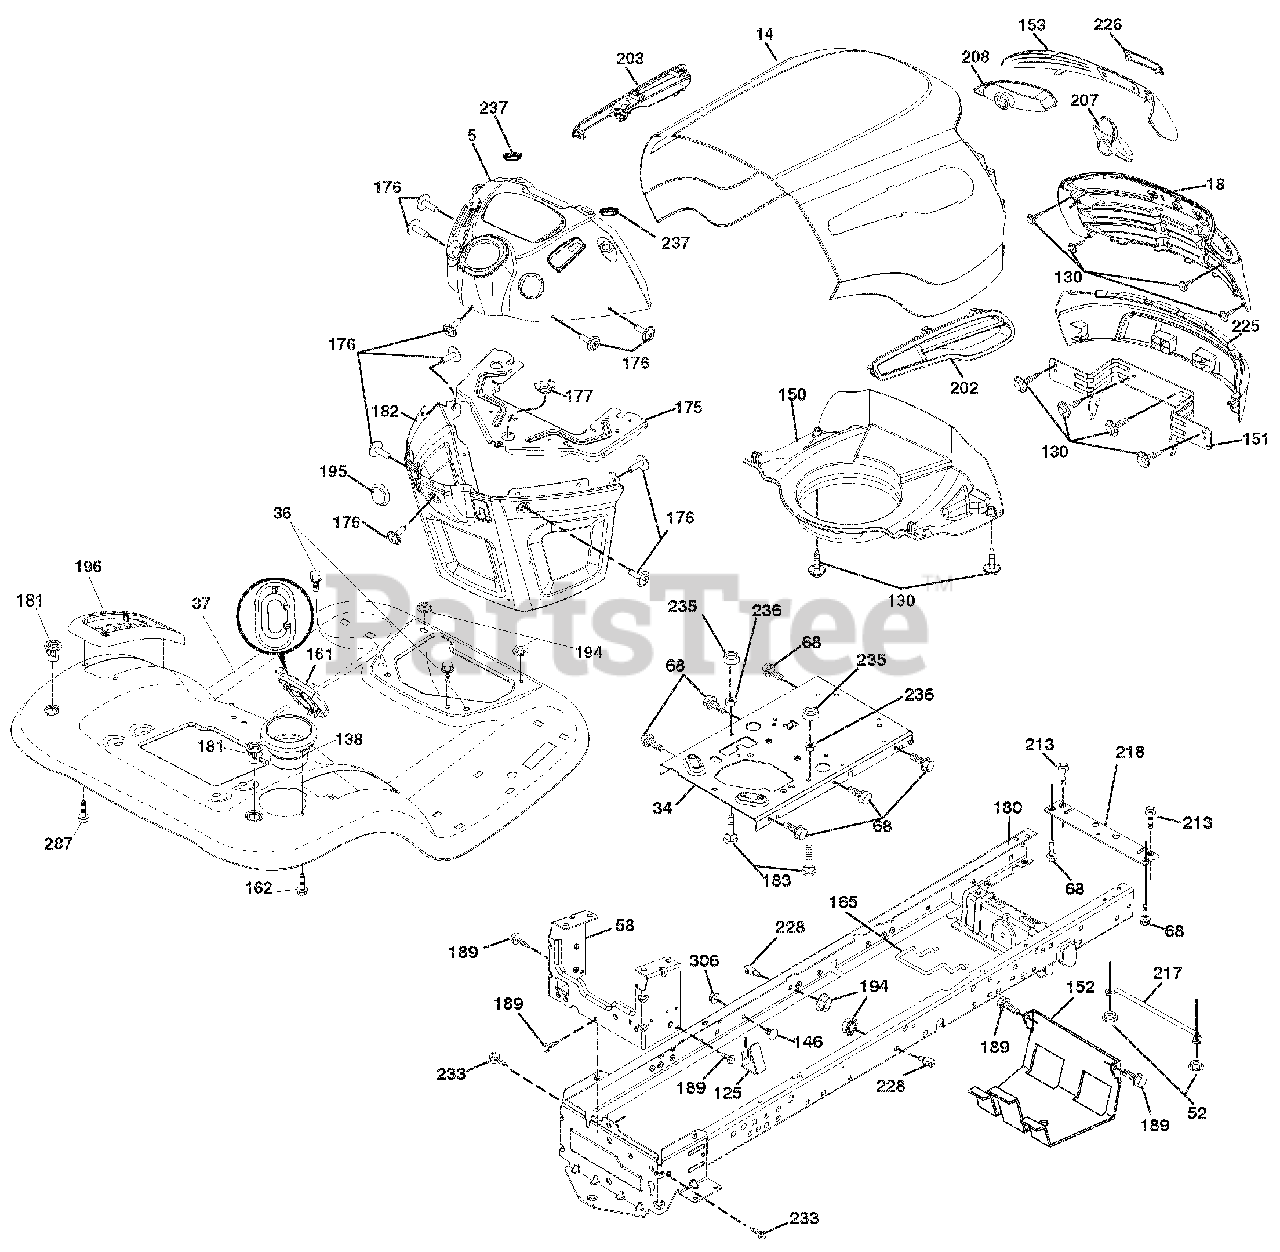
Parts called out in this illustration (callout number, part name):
5	DASH P/L TEX CABLE
18	GRILLE.ELITE.ARIENS.BLACK
34	PLATE.ENGINE.WELDED.CHASSIS
36	SCREW.5/16-18X3/4.SMGML.TAP/R
52	Nut, Hex, Crownlock 5/16-18
58	DRAWBAR.UPPER.2PC.SML.FENDER
68	SCREW.THDROL.5/16-18 X 1/2TYTT
125	CLIP.FUEL.LINE
138	CUPHOLDER TL TEX 428
150	AIR DUCT
151	BRACKET.PIVOT
152	SHIELD.BROWNING.W/TEX
153	LENS.BAR
161	WINDOW FUEL
162	SCREW.HEX.WSH.HI-LO.1/4X1/2UNC
165	SUPPORT.TANK.REAR.W/TEX
175	CROSSMEMBER.LT
176	SCREW.#10-24X5/8.RND.QUDRX.GIM
177	BUSHING.STEERING.LT
180	CHASS.WLDMT.TL.12GA/2PC.18/22"
181	BUSHING MNT FEND CRGO BLK TEX
182	DASH.LOWER.LT.CCS
183	BOLT.FIN.HEX.5/16-18 UNC X1-1/
189	SCREW.5/16-18X3/4.SMGML.TAP/BL
194	Nut, Lock Hex Flange 5/16-18 u
195	PLUG HOLE DASH TOWER
196	CONSLE.ASM.DECK.LFT.BL/RBT.TLT
202	VENT RH
203	VENT.SIDE.LH
207	BEZEL.RH
208	BEZEL.LH
213	BOLT.HEX.HD.1/4-20UNC X 3/4
217	ROD.PIVOT.HOOD
218	X-PIECE.HOOD.STOP.NON/STEALTH
226	ARIENS.LOGO.PLATE
228	STUD.FASTNER.W/'D'ANTI-ROTATIO
233	BOLT.SHOULDER
235	SPACER.FENDER
236	NUT.CENTER LOCK.5/16-18 UNC
237	PLUG.MOUNT.CARGO
287	SCREW.HEX.WASHEAD.1/4-20 X 3/8
306	Nut, Hex, Flangelock 3/8-16
